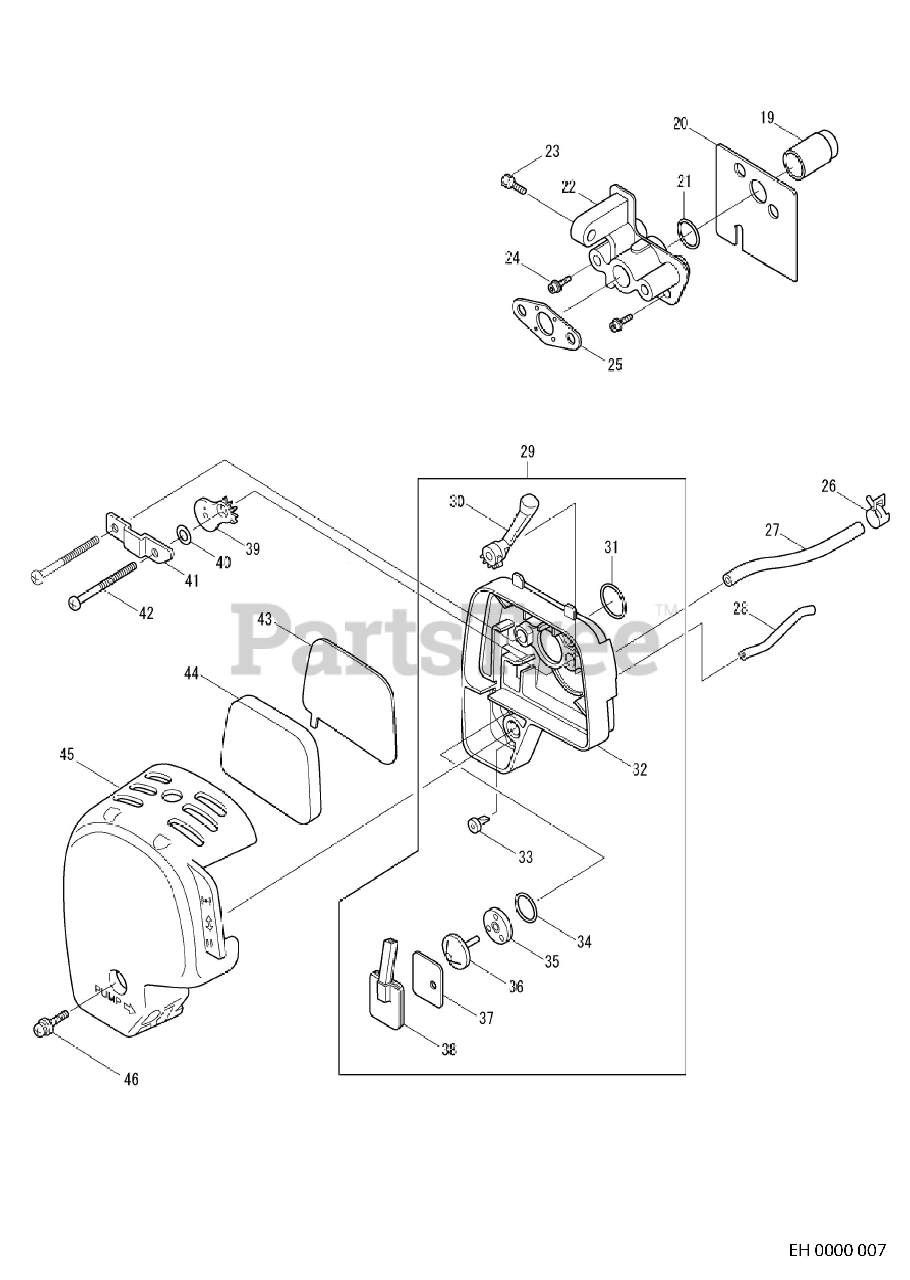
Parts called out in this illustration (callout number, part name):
19	PIPE, INTAKE
21	O-RING - 10
24	BOLT - M5×16
25	GASKET
26	CLAMP, HOSE
27	PIPE, BREATHER - 8.5X4.5
28	PIPE - 7X3X60
29	CLEANER PLATE ASSY
30	LEVER, CHOKE
31	O RING - 15
32	AIR CLEANER PLATE CP
33	VALVE, CHECK
34	O RING - 14
35	PLATE, CHECK VALVE
36	VALVE, CHECK
39	PLATE, CHOKE
42	SCREW - M5X68
43	ELEMENT, AIR CLEANER
44	ELEMENT, AIR CLEANER
45	COVER, AIR CLEANER
46	SCREW - M5X14
